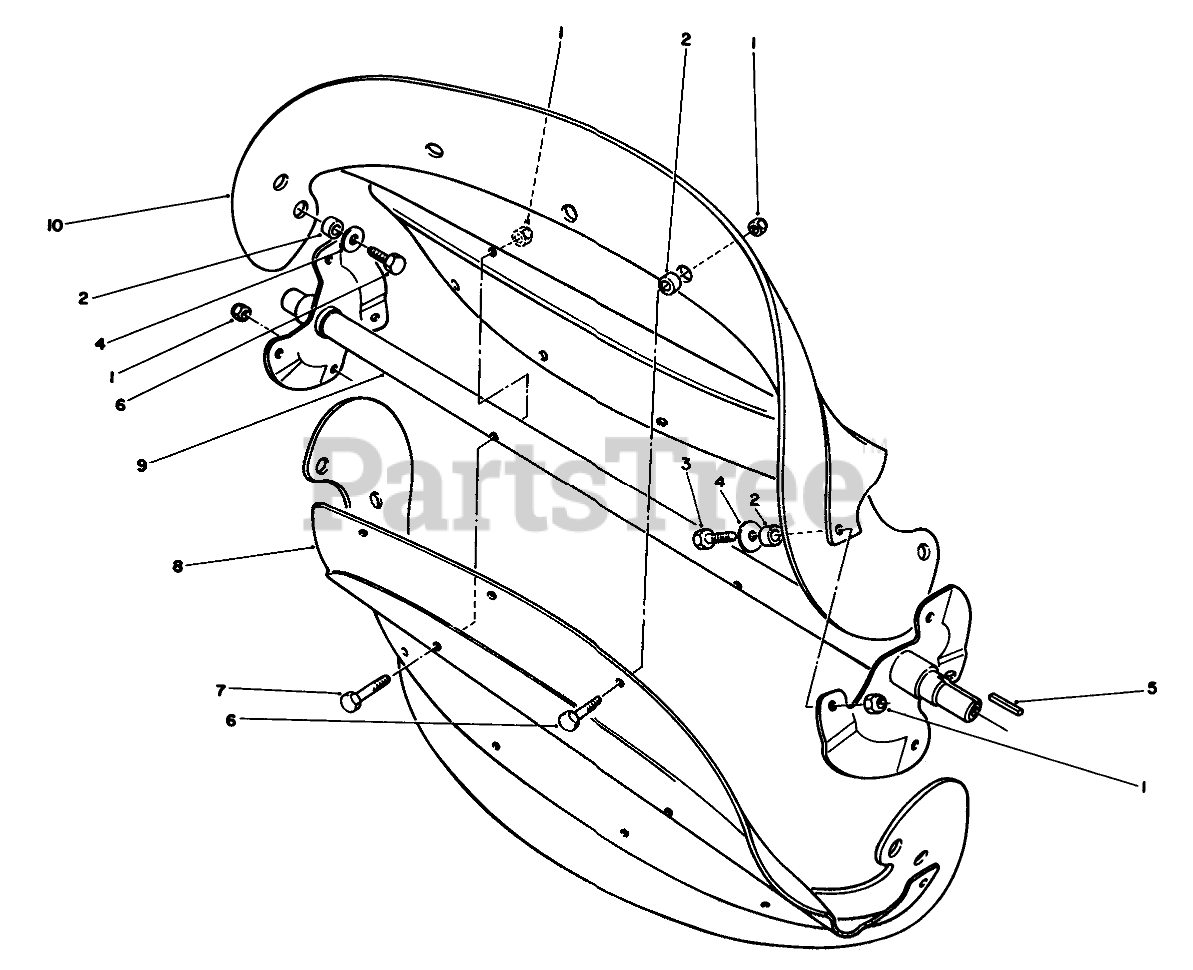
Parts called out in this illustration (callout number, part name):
1	NUT-LOCK, NI
2	SPACER-BLADE, ROTOR
3	SCREW-HH
4	WASHER-FLAT
5	KEY-SQUARE
6	SCREW-HH
7	SCREW-HH
8	ROTOR
9	Rotor Shaft Assembly
10	Blade-Rotor
